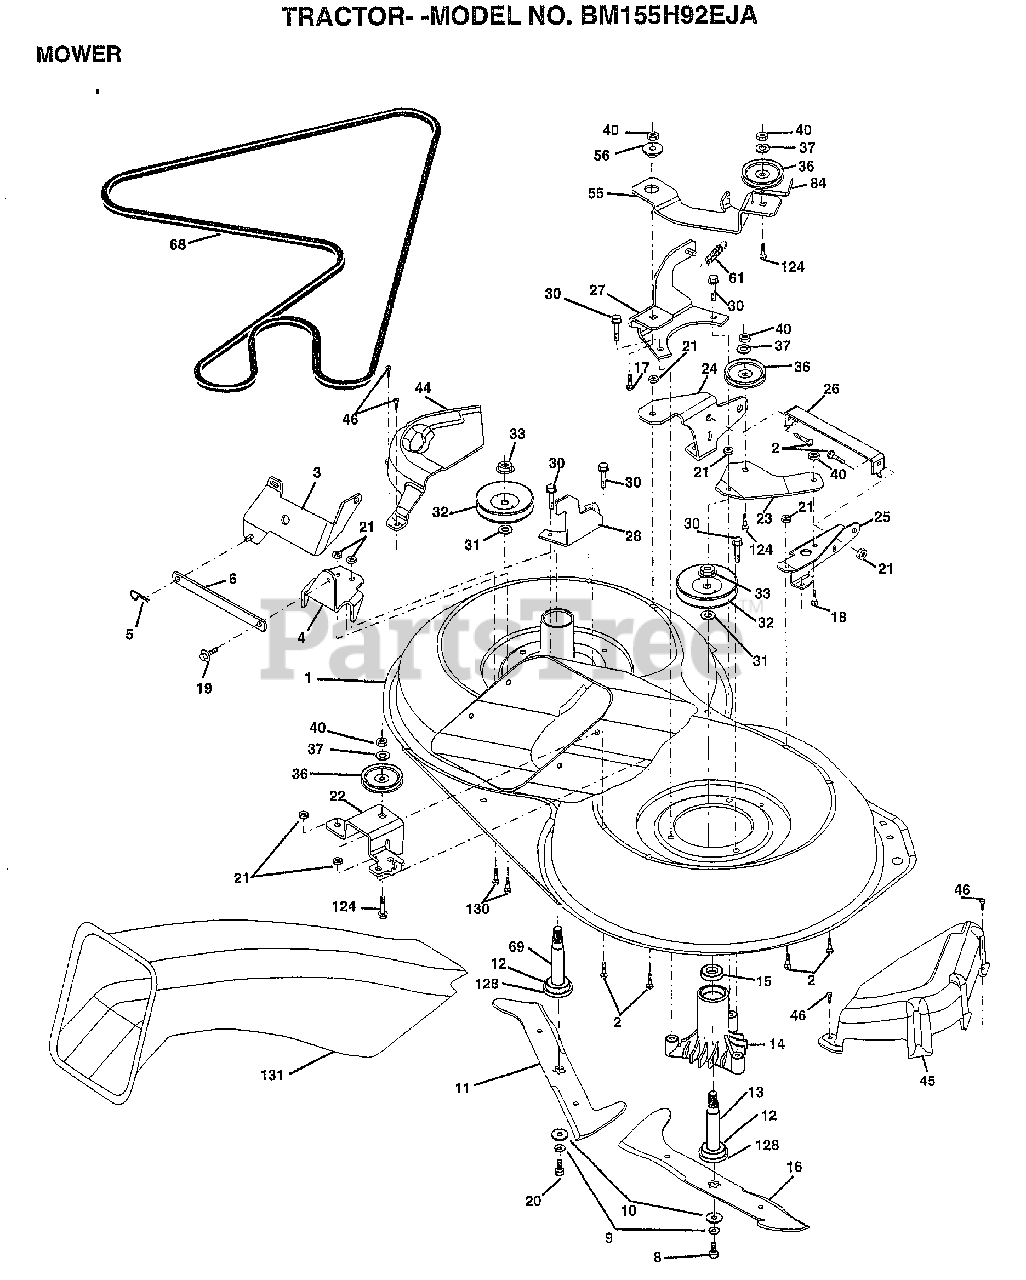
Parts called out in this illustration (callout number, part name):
1	HOUSING.ASM.MOWER
2	BOLT
3	BRKT.ASM.S-BAR.CHASSIS
4	BRKT.BAR.SWAY.DECK
6	BAR.SWAY.92.CRD
8	BLADE BOLT
10	WASHER.HARD.BLADE
11	BLADE.3-1.LH.92.CRD
12	BEARING.BALL
14	HSG ASM MANDREL
15	BEARING
16	BLADE.3-1.RH.CRD.92
17	BOLT.3/8-14X1.25
18	BOLT D
19	BOLT SHD 5/16-18
20	BOLT.3/8-24X1.25
22	BRKT.IDLER.SPRT.CRD
23	"BRKT.IDLER.SPRT.RF.92,CRD"
24	BRKT.SUSP.LF.92.CRD
25	BRKT.SUSP.RF.92.CRD
26	BRACE.SUPT.SUSP.FRT.CRD
27	BRKT.ASM.SUSP.RR.92.CRD
28	BRKT.ASM.SUSP.LR.92.CRD
30	"SCREW-THD ROLL,WA"
31	WASHER
32	PULLEY.MAND.36/46
34	BRKT.GUAGE.WHL.LF.92.CRD
35	BRKT.GUAGE.WHL.RF.92.CRD
36	PULLEY.IDLER.4.25
37	WASHER
44	COVER.MANDREL.LH.92.CRD
45	COVER.MANDREL.RH.92.CRD
46	SCREW.1/4-20X5/8
55	ARM.IDLER.92.CRD
56	SPACER RETAINER
61	SPRING.TENSION.BELT
68	HEX-BELT.92.MWR.105AA
69	SHAFT.ASM.W/LWR.BRG.RH.THD
84	"KEEPER-BELT,IDLER"
102	SCREW
103	WASHER #10
104	LOCKWASHER
105	LATCH ASSY.BAGGER
106	WELDNUT
116	BOLT.SHOULDER
117	WHEEL GAGE DONUT
118	LOCKNUT
119	WASHER
124	BOLT.3/8-16X1.50
128	WASHER.FELT.
131	CHUTE.BAGGER.CRD
